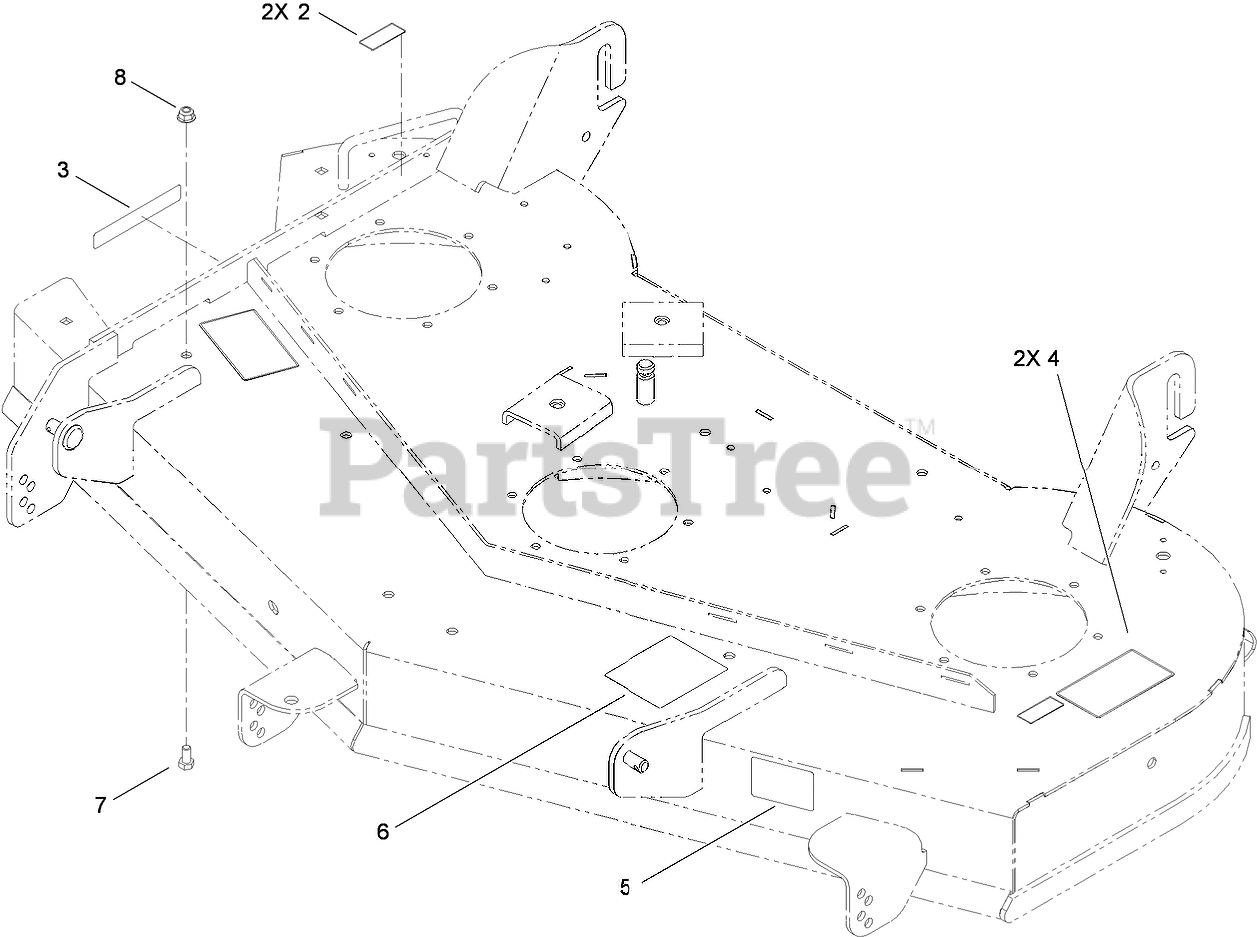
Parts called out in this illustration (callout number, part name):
2	DECAL-DANGER
3	DECAL-DANGER
4	DECAL-DANGER
5	DECAL-SCALP, ANTI
6	DECAL-ROUTING, BELT
7	SCREW-HH
8	NUT-HF, NI
